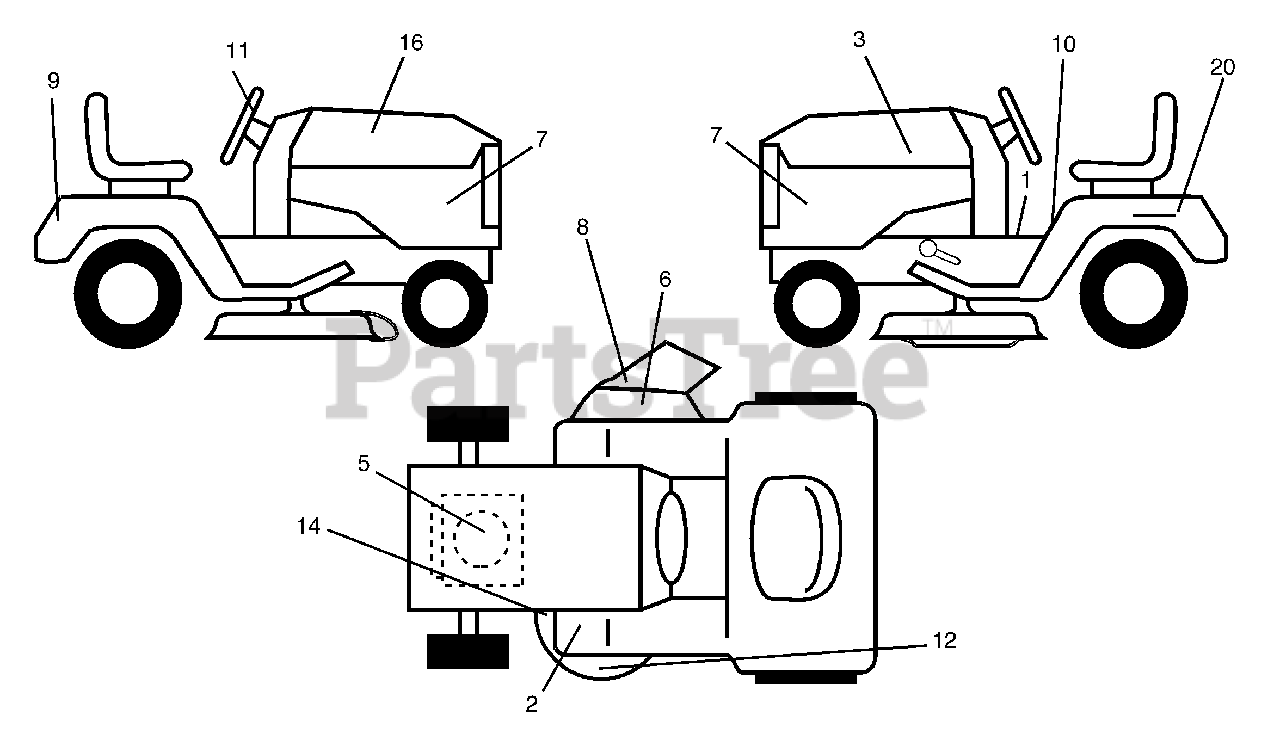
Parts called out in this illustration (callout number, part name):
1	Decal Oper
2	Decal Footrest
3	Decal Hood LH
4	Decal Replace
5	Decal HP Engine
6	Decal Deck "B" 42"
7	Decal Side Panel
8	Decal Warning Mult-Language
9	Decal Fender Logo
10	Decal Fender Danger E
11	Decal Ins Strg Whl
14	Decal V-Belt Schematic
16	Decal Hood Rh
20	Decal Bat Dan/Psn
